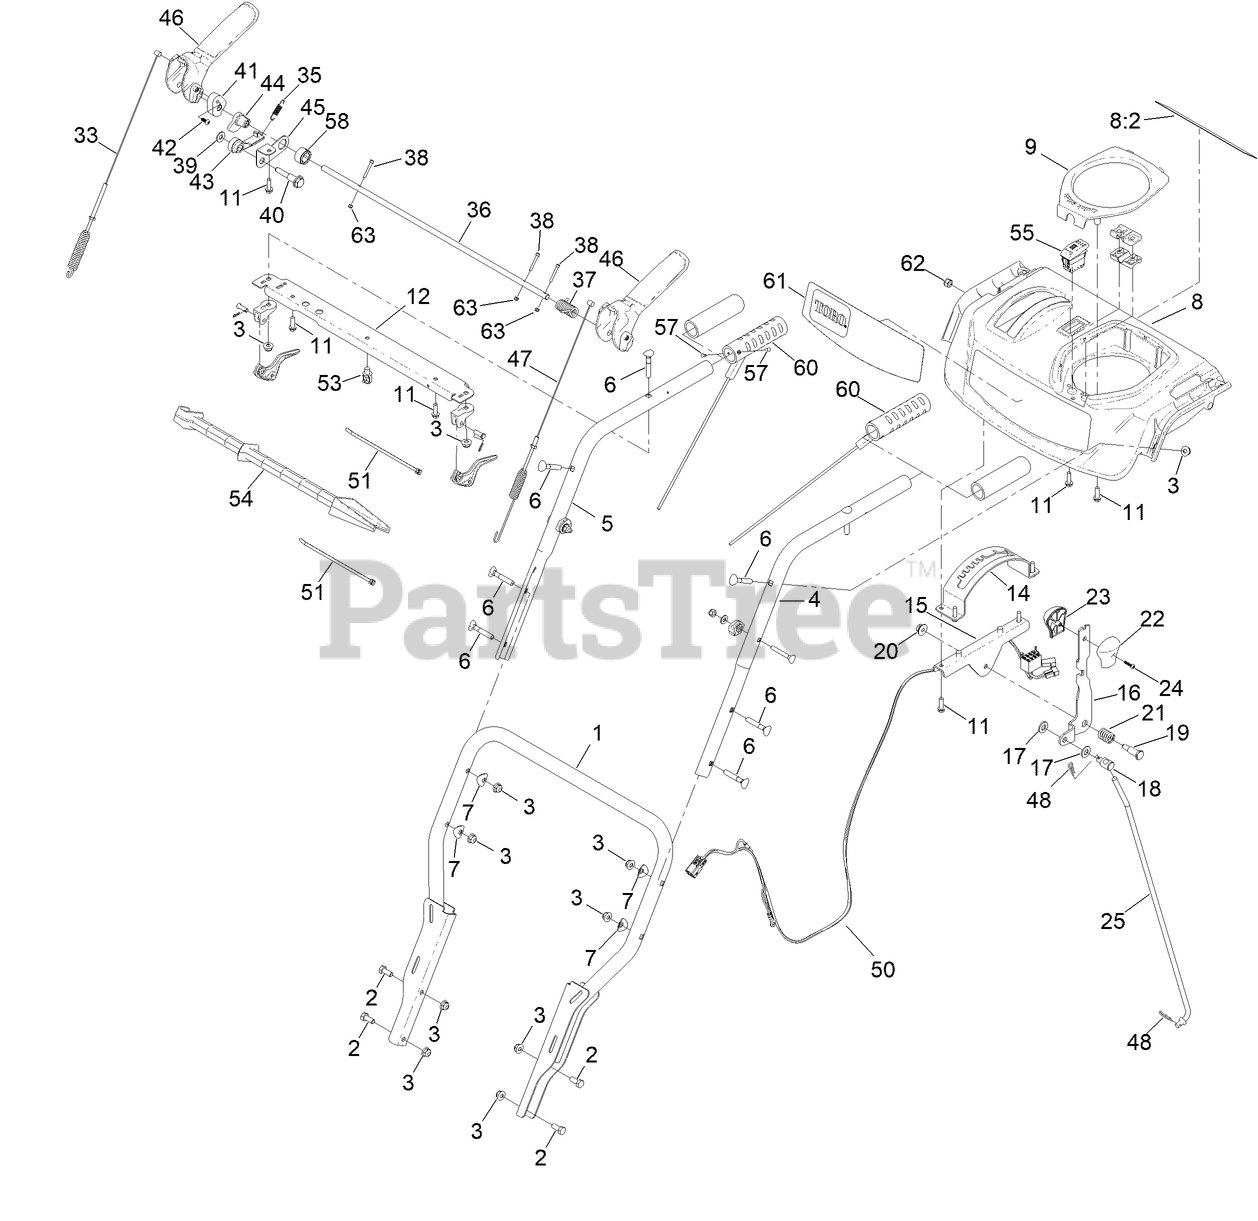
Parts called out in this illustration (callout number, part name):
1	HANDLE-LOWER, WELD ASM
2	SCREW-HH
3	NUT-HF
4	HANDLE-UPPER, LH
5	HANDLE-UPPER, RH
6	SCREW-HANDLE
7	WASHER-CUP
8	PANEL-CONTROL, ASSEMBLY
8:2	DECAL-SAFETY
9	COVER-QUICKSTICK
11	SCREW-PLASTITE, HWH
12	BRACE-CONSOLE
14	GATE-SHIFT
15	BRACKET-SHIFT
16	SELECTOR-SPEED
17	WASHER-FLAT
18	TRUNNION-ROD
19	SCREW-SHOULDER, HH
20	NUT-HF
21	SPRING-COMPRESSION
22	KNOB-SHIFT, LH
23	KNOB-SHIFT, RH
24	SCREW-PPH
25	ROD-SHIFT
33	CABLE-AUGER
35	SPRING-LOCKOUT, HANDLE
36	ROD-LOCKOUT
37	SPRING-TORSION, HANDLE RETURN
38	SCREW-HSH,SPL
39	WASHER-FLAT
40	SCREW-SHOULDER
41	HANDLE LOCK
42	SCREW-PPH
43	LATCH, LOCKOUT
44	CAM-LOCKOUT
45	LINK-LOCKOUT
46	LEVER-CONTROL
47	CABLE-TRACTION
48	PIN-HAIR
50	HARNESS-WIRE, LED AND HAND WARMERS
51	TIE-CABLE
53	CLIP-TIE
54	STICK-CLEANOUT
55	SWITCH-ROCKER, ON-NONE-OFF (HEATER)
57	RIVET-POP
58	COLLAR-CAM
60	GRIP-HEATED
61	DECAL-CONSOLE
62	NUT-HEX
63	NUT-LOCK ROHS
